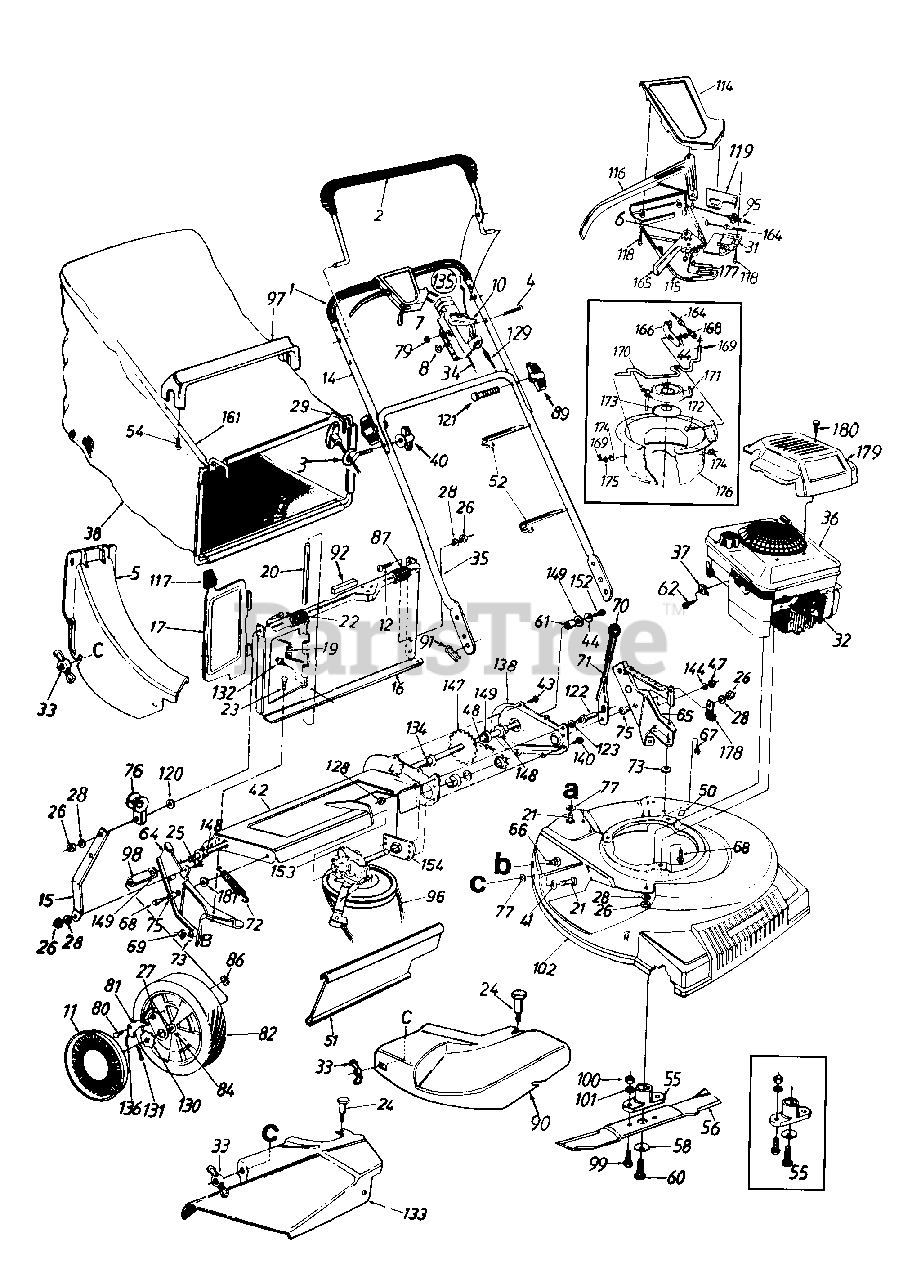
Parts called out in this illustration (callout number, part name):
1	Foam Grip
2	Control Handle
4	Oval C-Sunk Scr.
5	Rear Discharge Chute Ass'y.
6	3 Tooth Rack Gear Insert
7	Throttle Body
8	Spr. Wash..66" I.D.
10	Throttle Lever
11	Hub Cap
12	Truss Mach. Scr. 1/4-20 x .62"
21	Carriage Bolt 1/4-20 x .62"
22	Truss Mach. Scr. 1/4-20 x .75"
23	Hex AB-Tap Scr. 1/4-20 x .38"
24	Shoulder Bolt Special
25	Hex Bolt 1/4-20 x .62" Lg.
26	Hex Nut 1/4-20 Thd.
27	Pawl Plate
28	L-Wash. 1/4" I.D.
31	S.P. Control Cover
32	Spark Plug Insulator
33	Wing Nut
34	Throttle Cable 61"
36	Engine
37	Casing Clamp
38	Grass Bag
41	Fl-Wash..344" I.D. x .62"
44	Bell-Wash. 1/4" I.D.
47	Hex Patch L-Nut 3/8-24 Thd.
48	#48 Chain .500" Pitch x 30 Links
51	Rear Flap
52	Cable Tie
54	Hex AB-Tap Scr. #12 x 1.25"
55	Blade Adapter Kit
56	21" Mulching Blade
58	Bell-Wash..46" I.D.
60	Hex Bolt 7/16-20 x 1.5"
61	Spacer .513" I.D.
62	Hex Wash. Hd. Scr. #10-32 x .62" Lg.
64	R.H. Handle Wheel Brkt. Ass'y.
65	L.H. Handle Wheel Brkt. Ass'y.
66	Carriage Bolt 5/16-18 x .62"
67	Hex B-Tap Scr. 5/16-18
68	Hex TT-Tap Scr. 3/8-16
69	Hex Nut 5/16-18 Thd.
71	Height Adj. Lever
72	Extension Spring 3.80" Lg.
73	Bell-Wash. 5/16" I.D.
75	Shld. Spacer .5" Dia.
77	Bolt Retainer 1/4 x .50" O.D.
79	Hex L-Nut 1/4-20 Thd.
80	Shld. Scr..342" Dia. x .268
81	Pawl
82	Wheel Ass'y. Comp.
84	Sleeve Bearing 1/2" I.D.
86	Flat Nut 1/4-20 Thd.
89	Hand Knob
90	Mulching Plug
91	Hairpin Clip
95	S.P. Cable - 50" Lg.
96	"V"-Belt
98	Sleeve .526" I.D.
99	Hex Bolt 3/8-24 x 1.0" Lg.
100	Hex Nut 3/8-24 Thd.
101	L-Wash. 3/8" I.D.
115	Self-Propelled Control Cover
116	Control Lever
117	Door Grip
118	Fl-"C"-Sunk Hd. Tap Scr. 10 x .75" Lg.
119	6-Speed Rack Cable Brkt.
120	Fl-Wash..285" I.D. x 1.25" O.D.
121	Curved Hd. Bolt 5/16-18 x 2" Lg.
122	Shld. Pin 1.43" Lg.
123	L-Wash. 3/8" I.D.
128	Hex Jam Nut 3/8-24 Thd.
129	Control Cable - 44"
130	Ratchet Wheel 1.62" O.D.
131	Cotter Pin 1/8" Dia. x 1"
132	Hex B-Tap Scr. #10 x .38" Lg.
133	Side Chute Deflector Ass'y.
134	Hex Flange Bearing
135	Throttle Box Comp.
136	Spring - Nylon
144	Fl-Wash..385" I.D. x .87"
147	Rear Shaft Ass'y. 21.94" Lg.
148	Hex Flange Brg..506" I.D.
149	Fl-Wash..531" I.D. x .930"
152	Hex Bolt 1/4-20 x .62" Lg. (Gr. 5)
153	Transmission Comp.
164	Spd. Control Cable - 50" Lg.
165	6-Spd. Shift Lever
169	Cot-Pin 3/32" Dia. x .75" Lg.
171	Movable Pulley Half Ass'y.
172	Carr. Bolt 1/4-20 x .5" Lg.
173	Splined Pulley Half
174	Flanged Bushing
175	Fl-Wash..328" I.D. x .68" O.D.
179	Engine Cover
180	Screw #10 x 1.25" Lg.
181	Fl-Wash..383" I.D. x 1" O.D.
